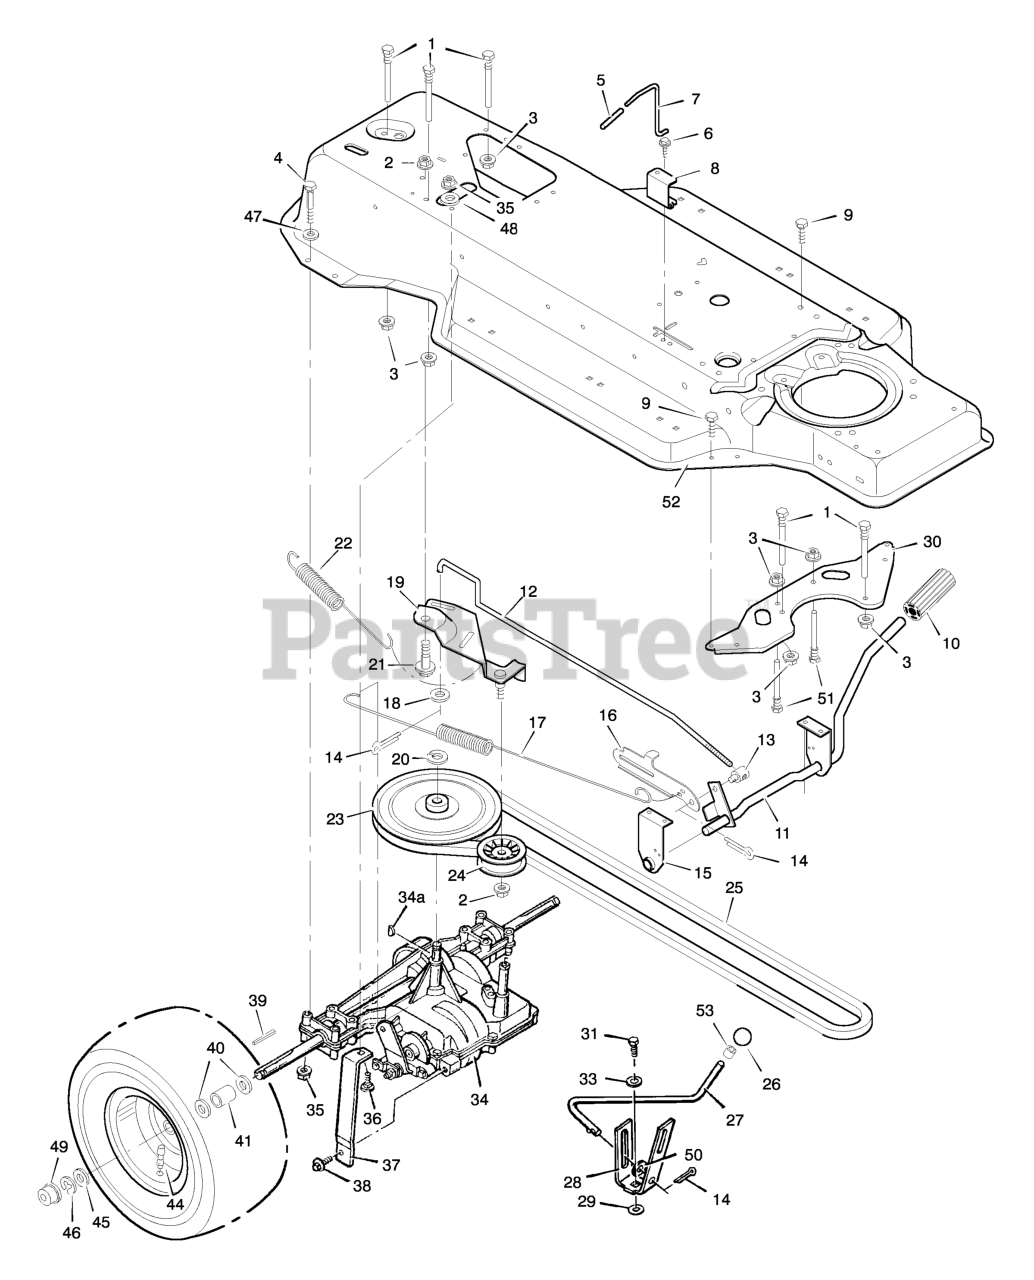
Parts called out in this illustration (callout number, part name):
1	Guide, Belt
2	Locknut, Flange
3	Nut, Flange
4	Bolt, Hex
7	Rod, Control
8	Guide, Bracket
10	Clutch and Brake Pedal
11	Lever Assembly
12	Rod, Clutch
13	Nut, Adjustable
14	Pin, Cotter
15	Bracket, Support
16	Latch, Park Brake
17	Spring, Brake Extension
18	Washer
19	Bracket Assembly, Idler
20	Ring, Retainer
21	Bolt, Shoulder
22	Spring, Drive Extension
23	Pulley, Motion Drive
24	Pulley, Backside Idler
25	Belt, Motion Drive
26	Knob, Shift Lever
27	Lever, Shift
28	Yoke, Shift
30	Plate, Belt Guide
31	Bolt, Hex
34	Transaxle, Peerless **
34A	Woodruff Key No. 9
35	Nut, Flange
36	Bolt, Carriage
37	Support, Transaxle
39	Key, Square
41	Spacer, Transaxle
43	Wheel & Tyre Assembly
44	Stem, Valve
47	Washer
49	Hub Cap
50	Washer
51	Guide, Belt
52	Frame Assembly
53	Ring, Tolerance
